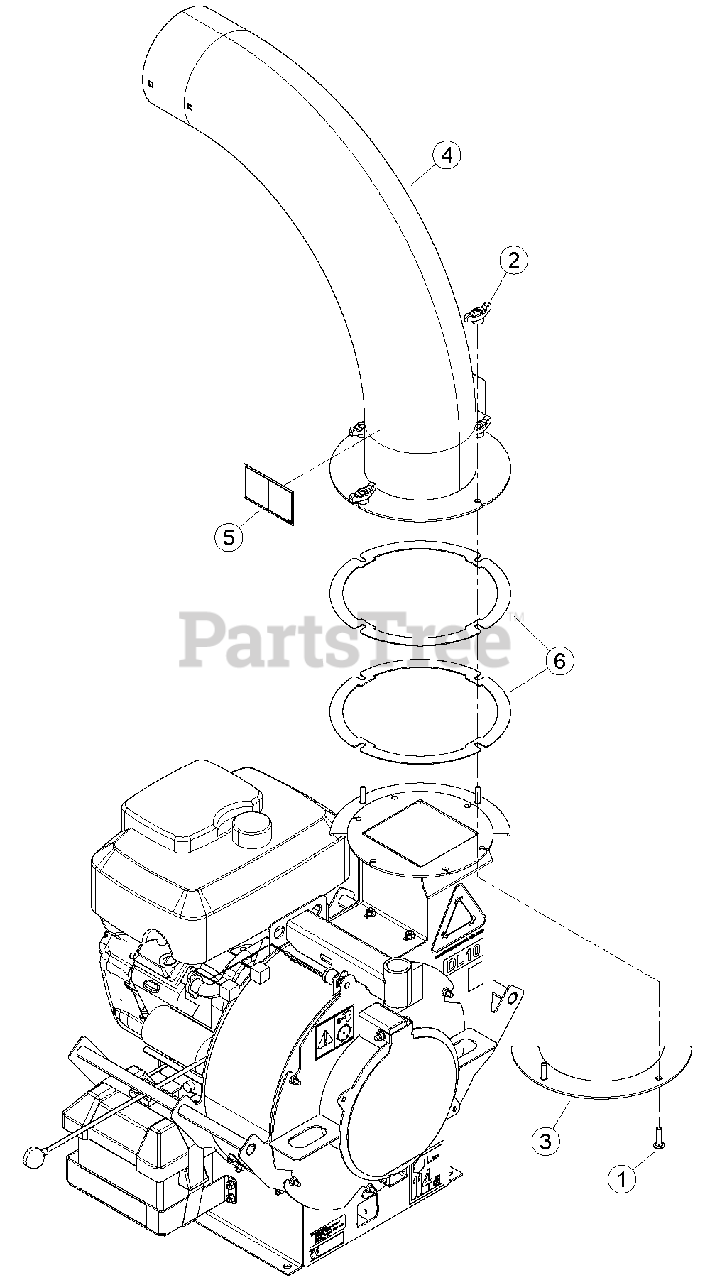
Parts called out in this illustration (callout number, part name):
1	BOLT, 3/8-16 X 1-1/2 GR5 CRG
2	KNOB, 3/8-16 UNC FEMALE TEE
3	RING, DL DISCHARGE
4	ASSEMBLY, DISCHARGE
5	DECAL, DISCHARGE ISO
6	RING, DL DISCHARGE
